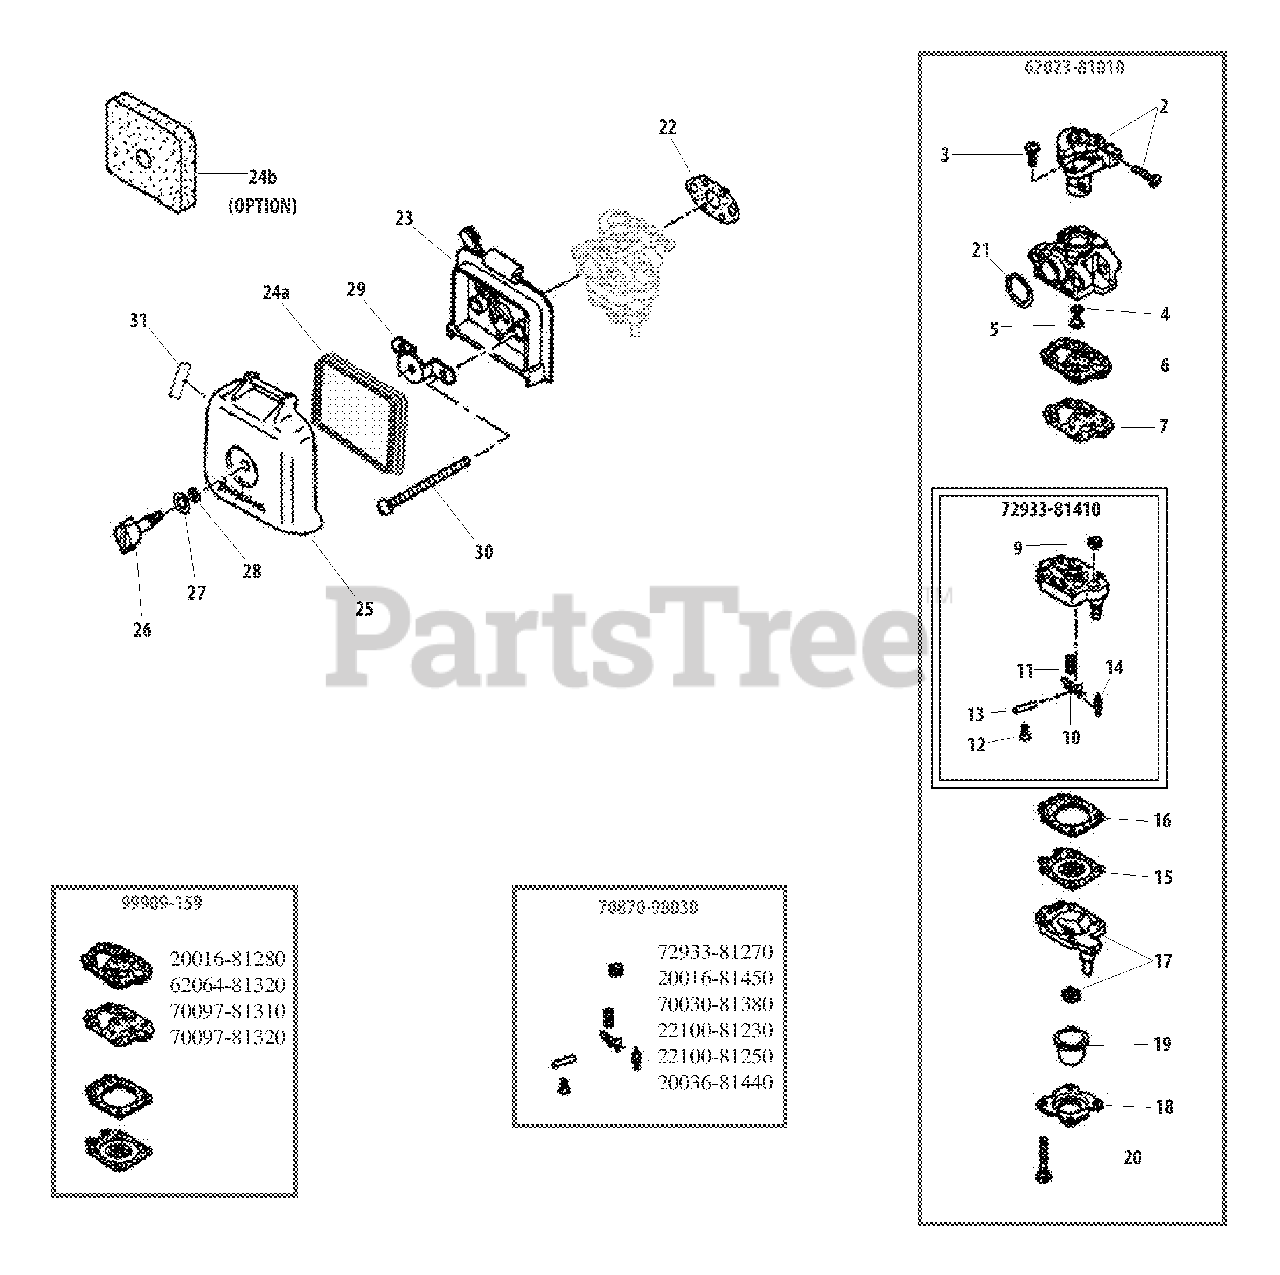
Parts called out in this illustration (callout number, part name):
2	VALVE, THROTTLE
3	SCREW
4	O-RING
5	JET, MAIN
6	GASKET, PUMP
7	DIAPHRAGM, PUMP
9	STRAINER
10	LEVER, METERING
11	SPRING, METERING LEVER
12	SCREW, METERING LEVER PIN
13	PIN, METERING LEVER
14	VALVE, INLET NEEDLE
15	DIAPHRAGM ASSY
16	GASKET, METERING
17	BASE, PURGE
18	RETAINER, PURGE BULB
19	BULB, PURGE
20	SCREW, PUMP COVER
21	O-RING - 15
22	GASKET
23	CASE, AIR FILTER
24A	FILTER, AIR - HEAVY DUTY
24B	FILTER, AIR - FOAM
25	COVER, AIR FILTER
26	THUMBSCREW
27	O-RING
28	WASHER - CONICAL
29	PLATE, PREVENT
30	SCREW - 5X67
31	LABEL - CHOKE
62023-81010	CARBURETOR
70870-98030	REPAIR KIT
99909-159	DIAPHRAGM/GASKET KIT
